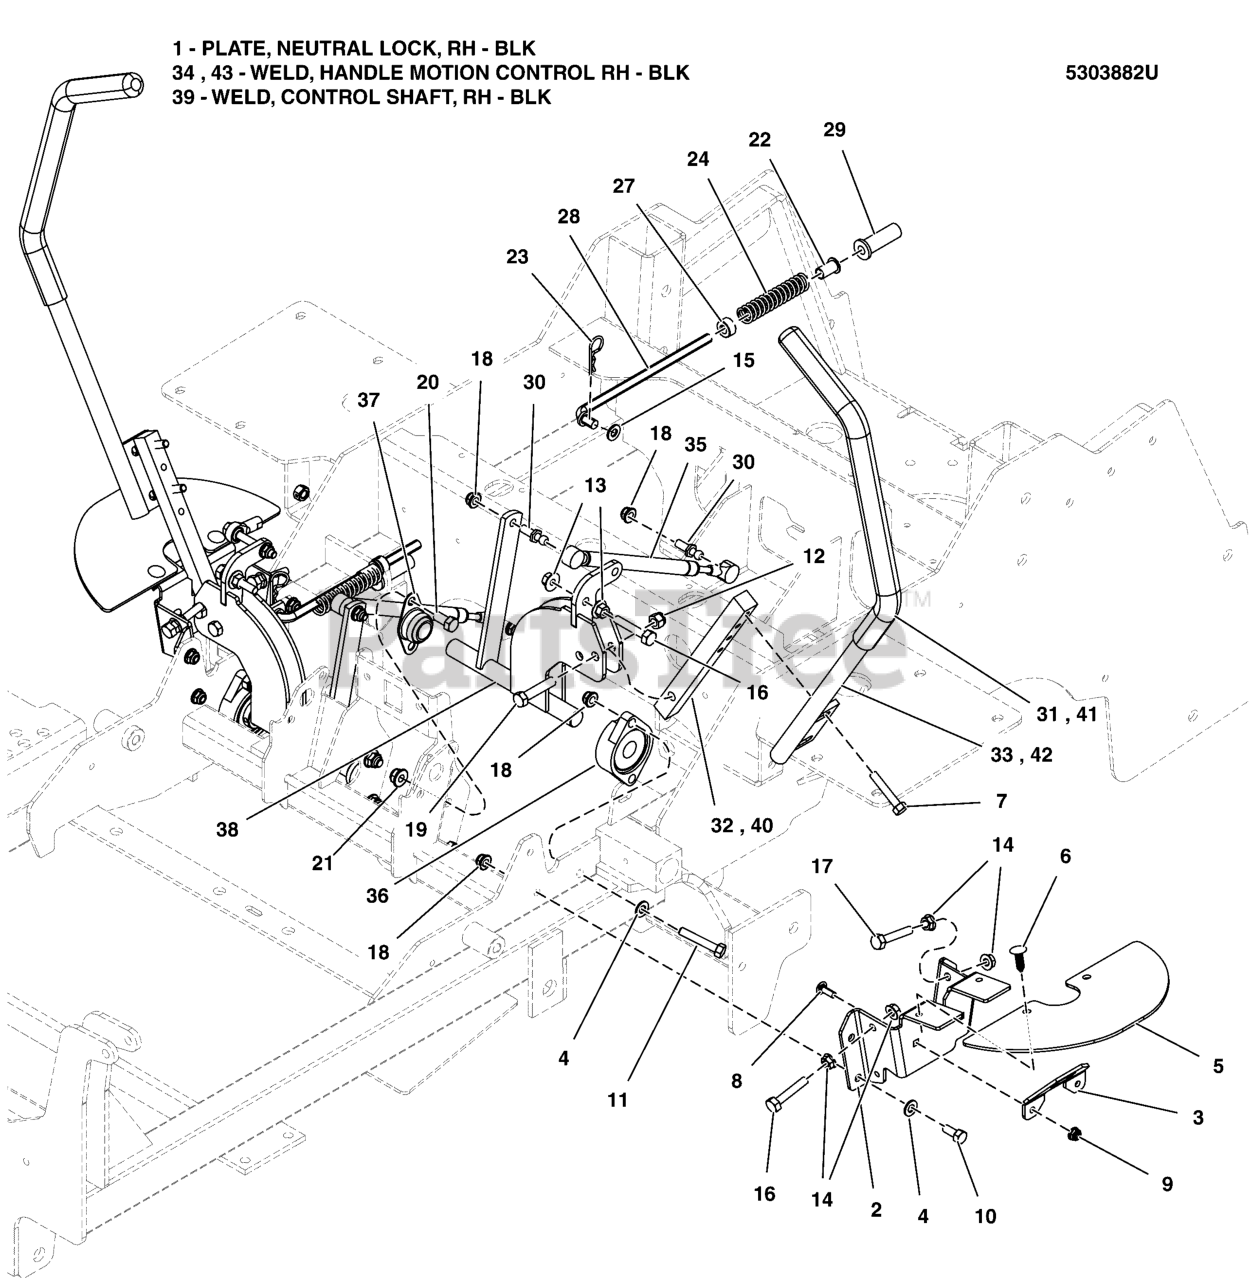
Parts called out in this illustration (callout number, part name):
1	PLATE, NEUTRAL LOCK, RH - BLK
2	PLATE, NEUTRAL LOCK, LH - BLK
3	BRACKET, SWITCH MOUNT - BLK
4	WASHER, 5/16" SAE
5	GUARD, RUBBER MOTION CONTROLS
6	PUSH RIVET (TREE TYPE), BLACK
7	SCREW, 5/16-18x0.750, GR5, WHIZ-LOCK, ZC
8	BOLT,1/4-20X.75,GR5,RH SH SQ NK,ZNC/CLR
9	NUT, 1/4-20 Hex Nylock Flange
10	BOLT, 5/16-18 X 3/4 GD5
11	BOLT, 5/16-18 X 3" GD5 YZ
12	NUT, 3/8-16 HEX NYLON LOCK
13	NUT, 5/16-18 HEX SERRATED FLANGE (LARGE)
14	NUT, 5/16-18 HEX SERRATED FLANGE (SMALL)
15	WASHER, 3/8 SAE
16	BOLT, 5/16-18 X 1-1/4 GD5 TFL, CZ
17	BOLT, 5/16-18 X 1-3/4 TFL, GD5 YZ
18	NUT, 5/16-18 HEX NYLOCK FLANGE NUT
19	BOLT, 3/8-16 X 1-3/4" GD5 CZ
20	BOLT, 3/8-16 X 3/4" GD5 CZ
21	NUT, 3/8 - 16 HEX NYLOCK FLANGE
22	BUSHING, FLANGE 3/8ID X 7/8 LONG
23	3/32 X 1-5/8 HAIR PIN CLIP
24	SPRING, REVERSE RETURN
25	BOLT, 7/16-14 X 3/4, GD 5 YZ
26	NUT, 7/16-14 HEX TOP LOCK
27	COLLAR, 3/8" Set
28	ROD, NEUTRAL RETURN, CZ
29	FLANGED BUSHING, 3/8IDX.63ODX.8125FL
30	10MM BALL STUD, 5/16-18 X 3/4 THDS
31	GRIP, FOAM, 3/4" ID, 16"" LONG
32	MOUNT, CONTROL ARM - BLK
33	WELD, CONTROL HANDLE-LH - BLK
34	WELD, CONTROL HANDLE-RH - BLK
35	DAMPENER, CONTROL,#(P6709/P3610)
36	BEARING, FLANGE
37	BEARING, BRONZE FLANGE, 3/4"
38	WELD, CONTROL SHAFT, LH - BLK
39	WELD, CONTROL SHAFT, RH - BLK
40	MOUNT, CONTROL ARM - BLK
41	GRIP, FOAM, 1" ID, 16" LONG
42	WELD, HANDLE MOTION CNTRL, 16.5, 1.0, LH - BLK
43	WELD, HANDLE MOTION CNTRL, 16.5, 1.0, RH - BLK
